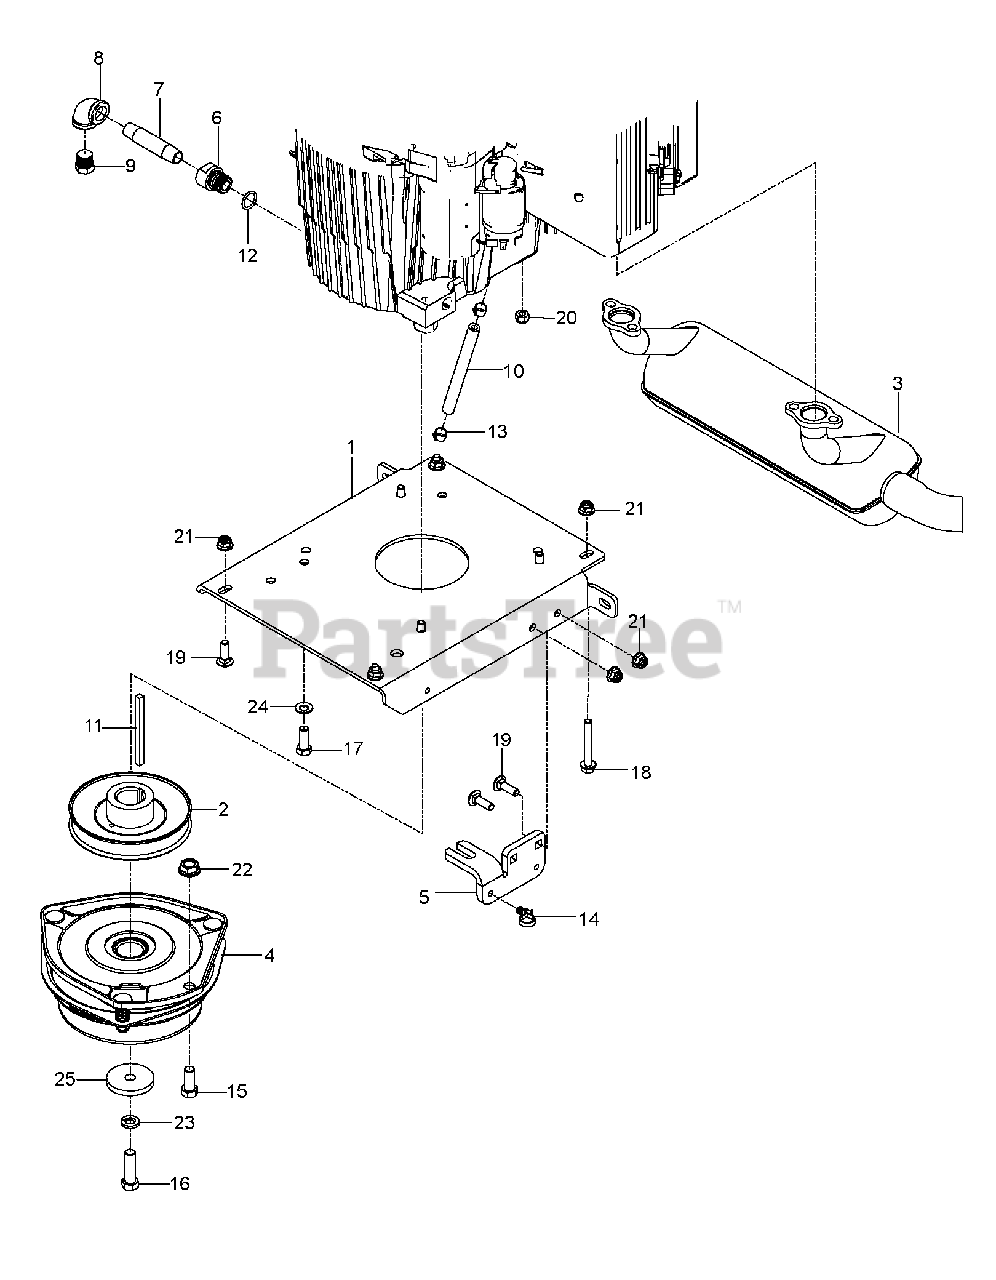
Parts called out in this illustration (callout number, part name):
1	PLATE.ENGINE.BLACK
2	PULLEY, ENGINE
3	MUFFLER, 29HP KAW FX751V-850V
4	CLUTCH, GT3.5
5	STOP, CLUTCH, OGURA
6	ADAPTER, OIL DRAIN
7	PIPE NIPPLE 3/8 X 3
8	90 DEG.ELBOW 3/8NPT
9	PLUG, DRAIN 3/8 NPTF
10	HOSE.1/4".LOW.PERM.FUEL.LN.14"
11	KEY, 1/4 SQ X 3.5
13	HOSE CLAMP
14	TIE WRAP, 8-3/8", W/CLIP
15	BOLT FIN HEX 7/16-14 X 1
16	CLUTCH BOLT7/16-20X1.5GR5.96HR
17	BOLT 3/8-16X1-1/8
18	HHFS 5/16-18 X 2.25 GD 5
20	NUT M8-1.25 TOP NYL GR10 ZD
21	5/16-18 NYLOC FLANGE NUT
22	NUT 7/16C WHIZ
23	WASHER 7/16 LOCK
24	WASHER, 3/8 DISC SPRING SPEC
25	BLADE WASHER
